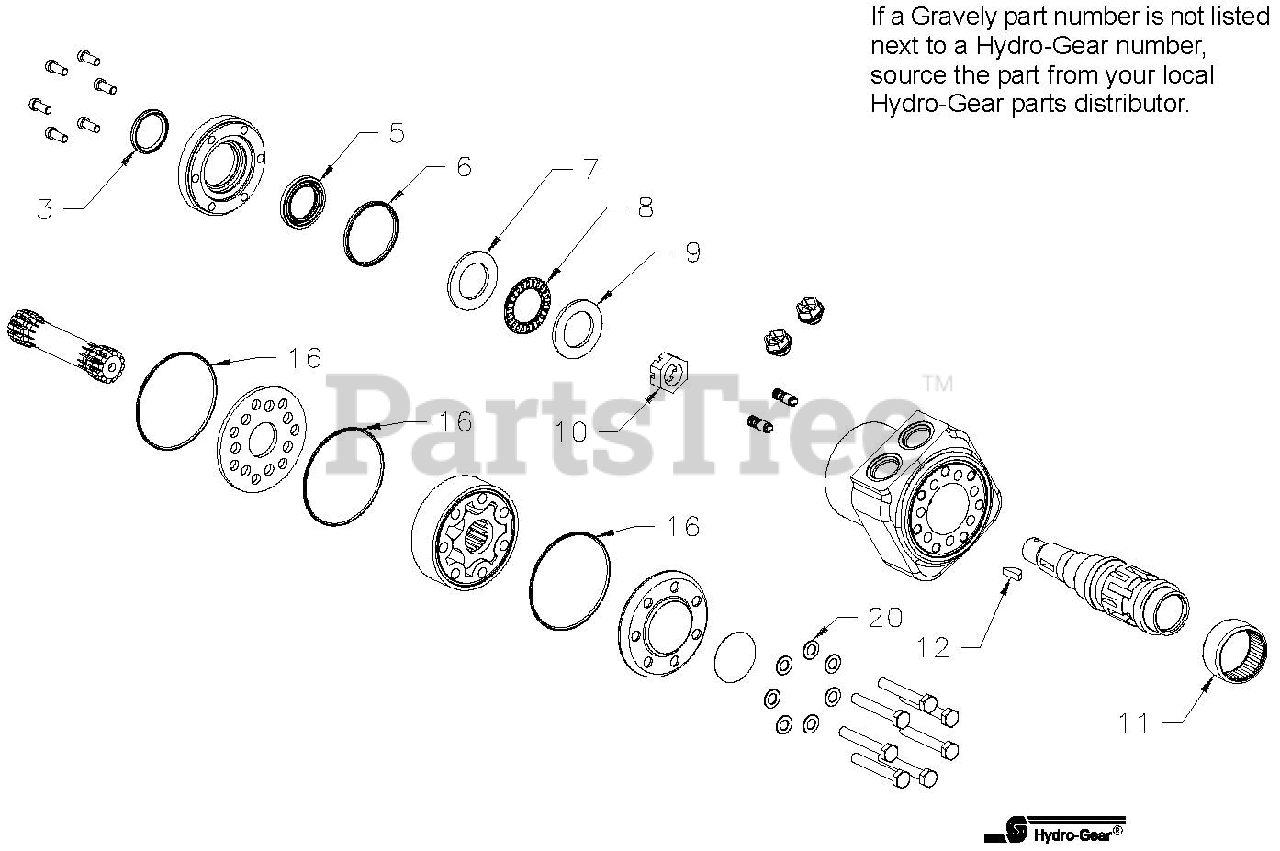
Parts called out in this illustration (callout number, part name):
10	Nut, Castle .75-20 Slotted Hex
12	Key, Woodruff .1875 x .75
NS	Seal Kit
NS	Kit, Axial Needle Bearing HGM P-Series
